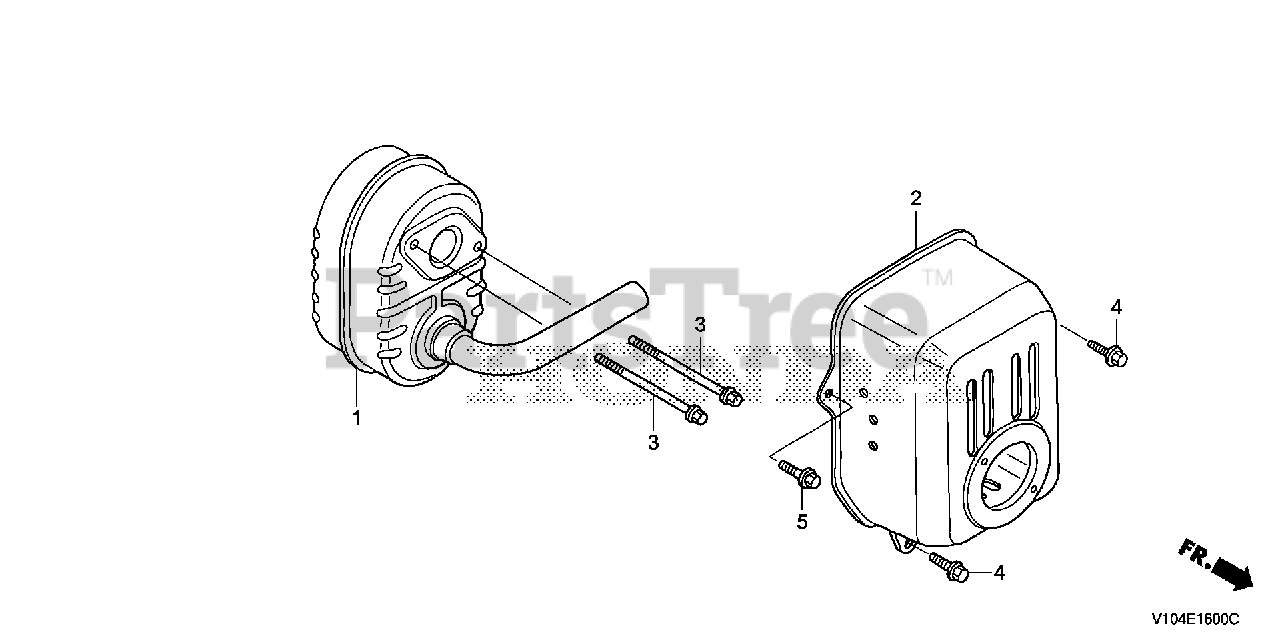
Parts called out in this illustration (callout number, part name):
2	PROTECTOR, MUFFLER
3	BOLT, FLANGE (6X79) (CT200)
4	BOLT, FLANGE (6X12) (CT200)
5	BOLT, FLANGE (6X14)
